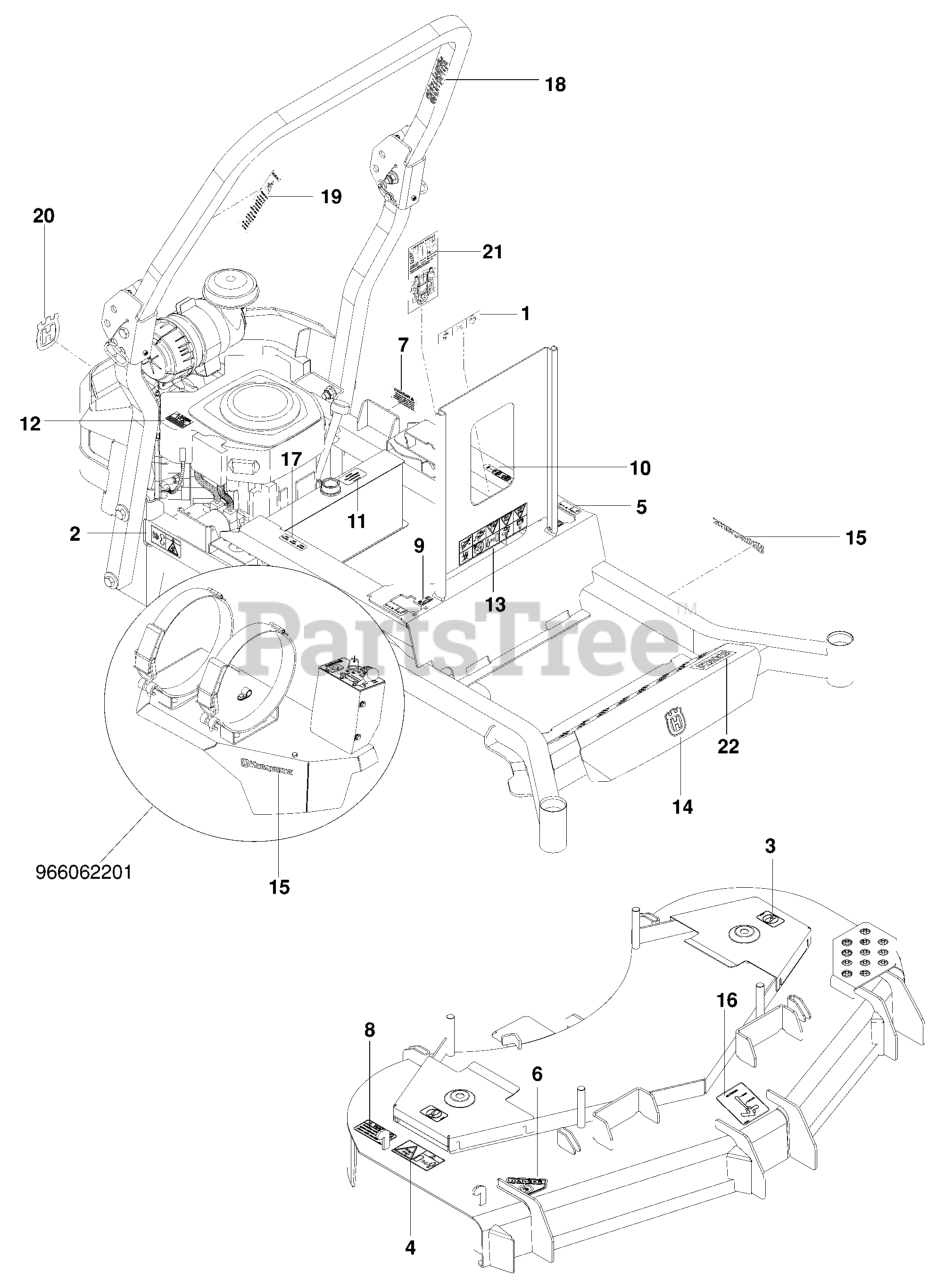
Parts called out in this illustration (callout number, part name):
1	EURO DECAL-BATTERY WARNIN6
2	DECAL, BELT DRIVE
3	DECAL, NO STEP
4	DECAL, EURO SEVERING
5	DECAL, MOTION CONTROL
6	DECAL, CPSC
7	DECAL, PROP. 65
8	DECAL, CAUTION
9	DECAL, F.S.T.
10	DECAL, PARK BRAKE
11	DECAL, OIL TANK
12	DECAL, EXHAUST
13	DECAL, WARNING
14	DECAL, CROWN H 70MM
15	DECAL.HOOD.LOGO.ORANGE.HUSQVAR
16	DECAL, BELT ROUTING
17	DECAL, FUSE
18	DECAL, ROPS
19	DECAL, ROPS, WARNING
20	DECAL, CROWN H, 110MM
21	DECAL, SERVICE
22	DECAL, PZ5426
